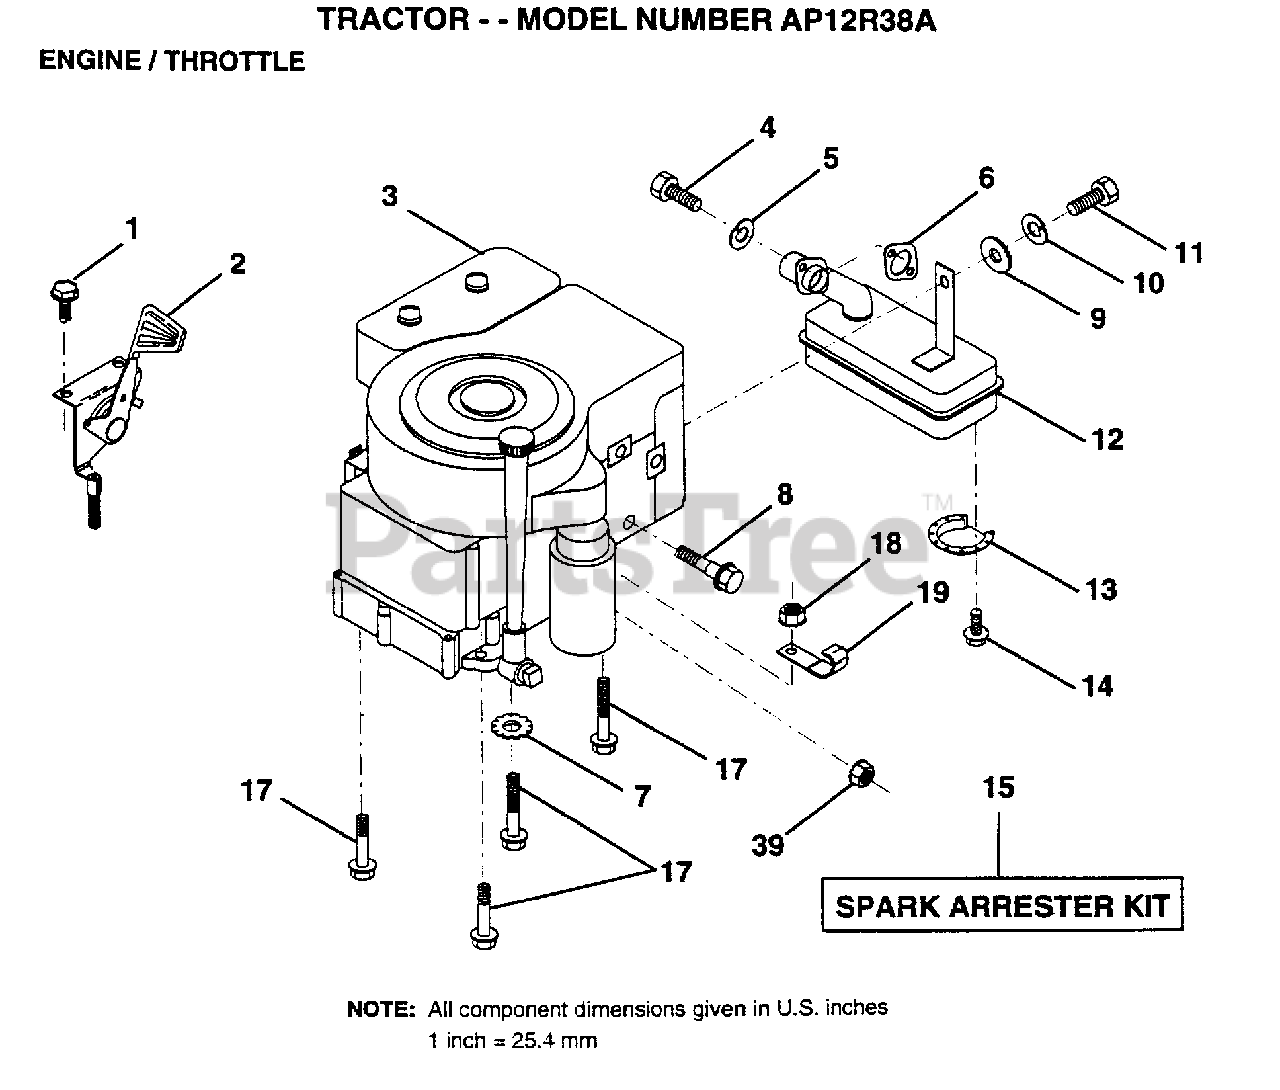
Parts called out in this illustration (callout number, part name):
1	SCREW.1/4-20X1/2
2	"CONTROL,THROTTLE"
3	ENGINE BRIGGS AND STRATTON
4	SCREW
5	LOCKWASHER
7	LOCKWASHER
8	BOLT T
10	LOCKWASHER
12	MUFFLER
13	DEFLECTOR.222573
17	SCREW LT
19	CLIP T
23	LOCKWASHER
39	NUT
